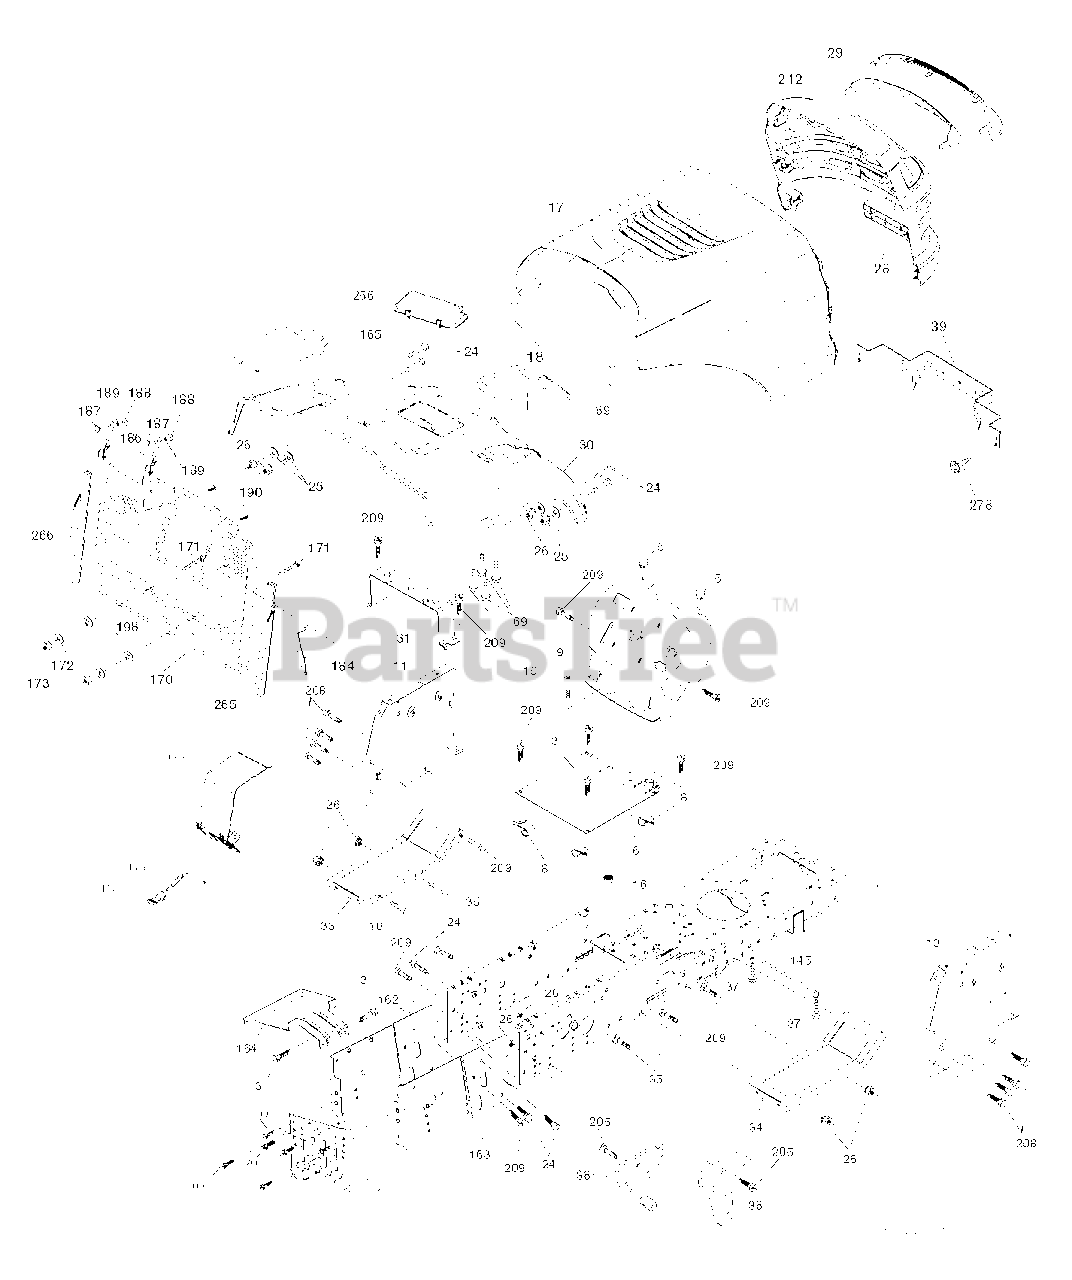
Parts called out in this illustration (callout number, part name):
1	CHASSIS
3	SCREW 3/8-16X3/4
5	BUMPER.RUBBER.HOOD
8	CLIP,INSULATOR
10	BOLT D
11	PANEL.DASH.LH.LTX
13	PANEL DASH RH
16	NUT
18	BUMPER.HOOD.LARGE.1.75"
25	WASHER
26	NUT
31	BRACKET SUPPORT FENDER
39	BRACKET PIVOT
69	SCREW.HI-LO.CONSOLE
145	ROD.PIVOT.HOOD
164	SUPPORT
171	BOLT
172	WASHER
186	LATCH ASSY
187	WELDNUT
189	LOCKWASHER
207	SCREW, 5/16-18 X 1/2
208	SCREW 3/8-16X1/2
209	SCREW, 3/8-16X3/4
278	SCREW.#10 X 0.750.BOS THREAD
